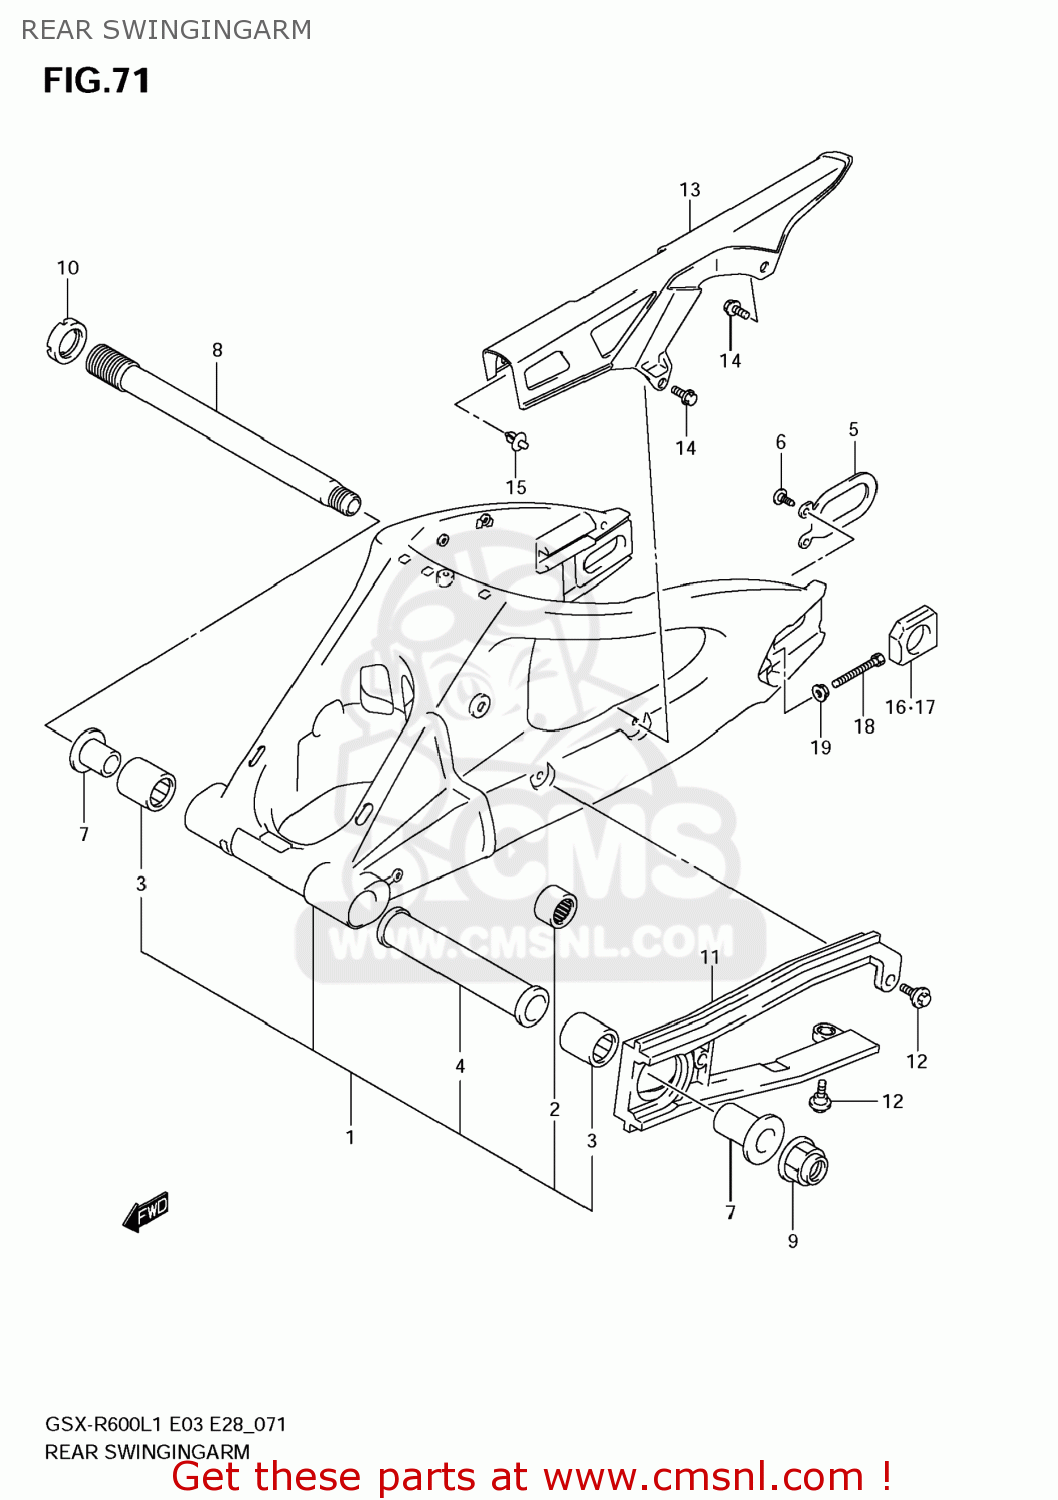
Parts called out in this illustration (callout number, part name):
1	SWINGINGARM ASSY,RR
2	BEARING(20X27X30)
3	BEARING(27X35X35)
4	SPACER,RR SWG PVT CTR
5	PLATE,RR SWING ARM BRKT
6	SCREW(6X12)
7	SPACER,RR SWGARM PIVOT BEARING
8	SHAFT,RR SWINGINGARM PIVOT
9	NUT
10	NUT,REAR SWGAR
11	BUFFER,CHAIN TOUCH DEFENSE
12	BOLT(6X17.8)
13	CASE,CHAIN
14	BOLT(6X12)
15	CLIP(BLACK)
16	ADJUSTER,CHAIN,R
17	ADJUSTER,CHAIN,L
18	BOLT(8X50)
19	NUT
